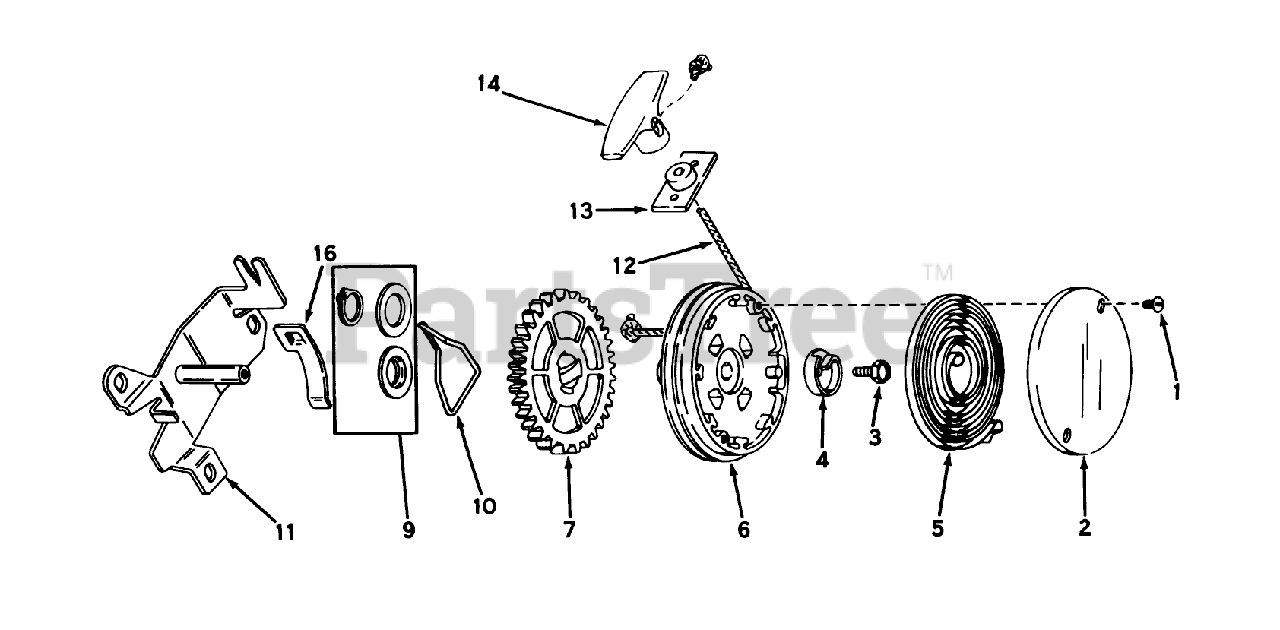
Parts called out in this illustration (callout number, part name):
1	Screw, Cover
2	Cover, Spring
3	Screw, Hex Washer Head
4	Hub Spring
5	Spring, Rewind
6	Pulley Assy. (Incl. No. 9)
9	Kit, Thrust Wash. Snap Rg.
10	Brake
11	Bracket Assy. Mounting
12	Rope, Starter
13	Bracket Assy.
14	Handle-Starter
16	Clip Rope
